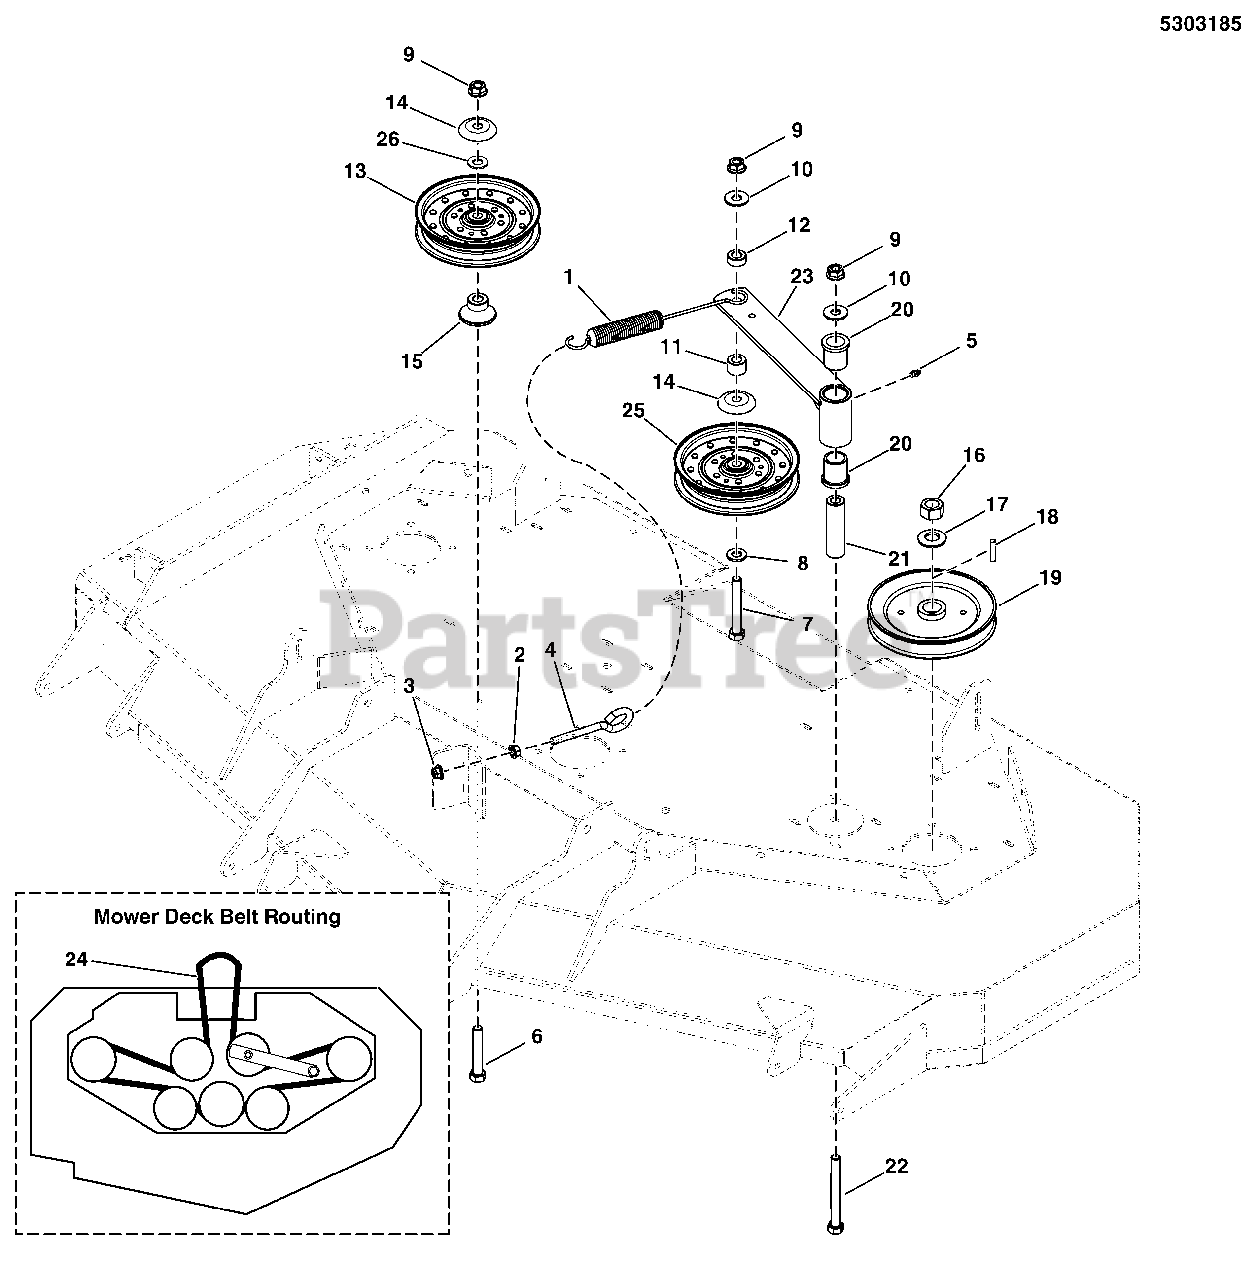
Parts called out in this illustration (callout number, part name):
1	SPRING, EXTENSION, SWIVEL. LONG HOOK
2	NUT, 3/8-16 HEX SERRATED FLANGE
3	NUT, 3/8-16 HEX NYLOCK FLANGE
4	EYE BOLT, 3/8-16 X 8, 1 EYE
5	GREASE FITTING, 1/4-28 STRAIGHT
6	BOLT, 1/2-13 X 3" GD5 CZ
7	BOLT, 1/2-13 X 2-3/4 GD5 CZ
8	WASHER, 1/2 GD9 YZ
9	NUT, Hex Flange, Nylock, 1/2-13
10	WASHER, 1/2 USS
11	SPACER, .52 X 1.00 X .56, CZ
12	SPACER, .52 X 1.00 X .22, PM, CZ
14	SHIELD, PULLEY BEARING
15	IDLER MOUNT
16	NUT, 3/4-16 HEX
17	WASHER, 3/4 BELLEVILLE
18	KEY, 1/4 SQ X 1-1/4
19	PULLEY, 6.93 EOD X 25MM, SPLIT
20	BUSHING, FLANGE
21	SPACER, .52 X 1.00 X 3.50
22	BOLT-1/2-13 X 5 GD5 YZ
23	WELD, IDLER ARM - 52" - BLK
24	BELT, 5V, 175.90EL, LG ARAMID, WRPD, RC
26	WASHER, 1/2 SAE
